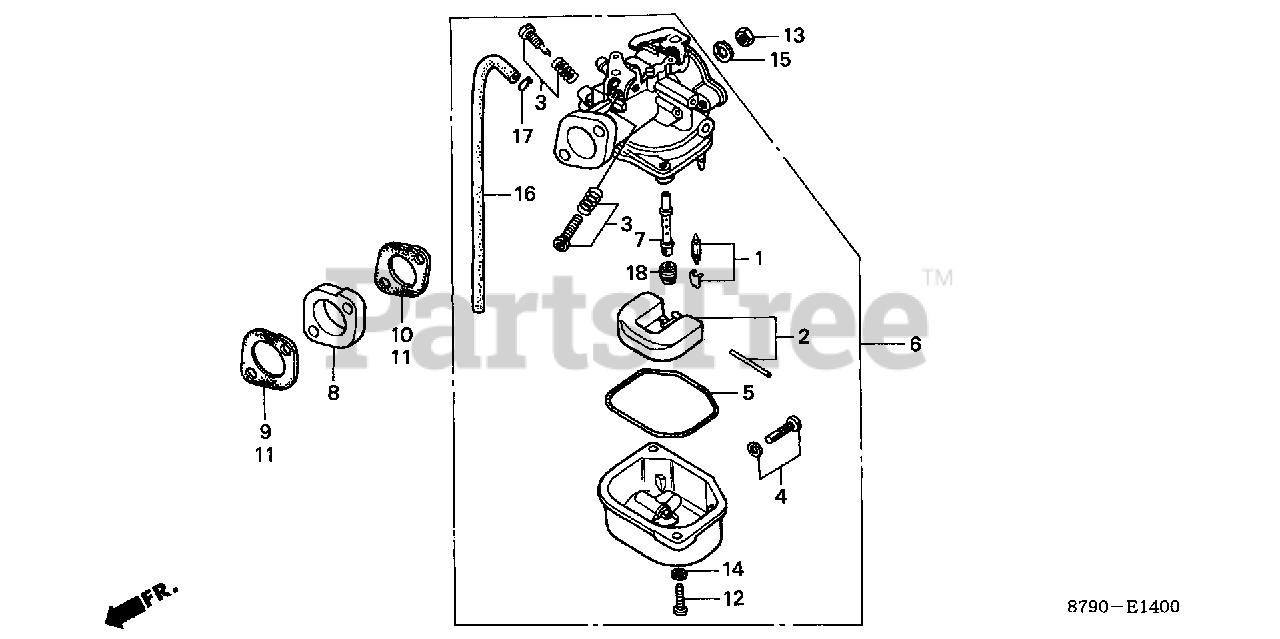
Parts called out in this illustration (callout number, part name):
1	VALVE SET, FLOAT
2	FLOAT SET (CARBURETOR NO.)
3	SCREW SET (CARBURETOR NO.)
4	SCREW SET, DRAIN
5	O-RING (NOT AVAILABLE)
6	CARBURETOR ASSY. (BB03B E)
7	NOZZLE, MAIN (NOT AVAILABLE)
8	INSULATOR, CARBURETOR (NOT AVAILABLE)
8	INSULATOR, CARBURETOR
9	GASKET A, CARBURETOR INSULATOR (NOT AVAILABLE)
10	GASKET B, CARBURETOR INSULATOR (NOT AVAILABLE)
11	GASKET, CARBURETOR INSULATOR (NOT AVAILABLE)
12	SCREW, PAN (4X12)
13	NUT, HEX. (6MM)
14	WASHER, SPRING (4MM)
15	WASHER, SPRING (6MM)
16	BULK HOSE, FUEL (3.5X3000) (3.5X120) (CARBURETOR NO.)
17	CLIP, TUBE (B7) (CARBURETOR NO.)
18	JET, AIR (#68) (CARBURETOR NO.) (NOT AVAILABLE)
18	JET, AIR (#70) (CARBURETOR NO.) (NOT AVAILABLE)
